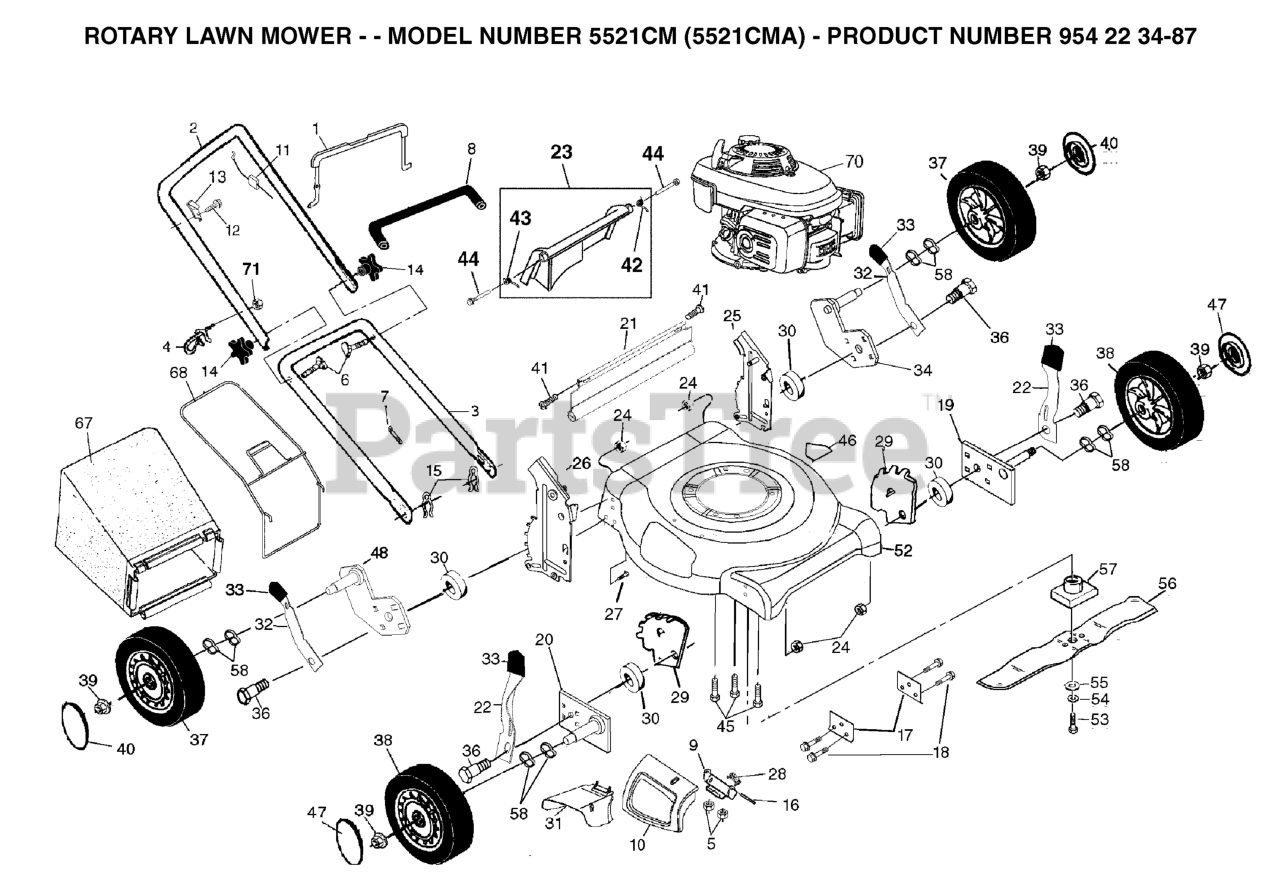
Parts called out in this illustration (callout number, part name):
1	CONTROL BAR
2	UPPER HANDLE, WITH GRIP
3	HANDLE.LOWER.GREY
4	ROPE, GUIDE
5	NUT
6	HANDLE BOLT
7	TIE GUIDE
8	GRIP.HANDLE.FOAM
9	BRACKET.ASM.HOUSING.EZ.MUL
10	RP DOOR.MULCH.21".REAR.PUSH.GR
11	ENGINE ZONE CONTROL CABLE
13	BRACKET
14	KNOB.HANDLE.STAR.HUSQ.GRAY
15	HAIRPIN COTTER
16	ROD.HINGE.COMBI-C
17	SUPPORT BRACKET
18	SCREW 1/4X20
19	AXLE ARM ASM (L)
20	AXLE ARM ASM
21	REAR DEFLECTOR, POULAN PR6N22
22	REPL BY 532 1683-60
23	REAR DOOR ASSEMBLY KIT
24	NUT.CENTERLOCK.5/16-
25	HANDLE BRACKET ASSEMBLY, LEFT
26	HANDLE.BRKT.ASSY.RIGHT.BLACK
27	SCREW
28	TORSION SPRING
29	WHEEL BRACKET ADJUSTER
30	SPACER.34X1.38X.22
31	DEFLECTOR.CLIPPING.21.GREY
32	SELECTOR SPRING, REAR
33	SELECTOR KNOB
34	AXLE ARM ASSY 10"
36	SHOULDER BOLT
37	WHEEL.10X2.PR.HITRAC.BLACK
38	WHEEL 8 X 2 BLACK BALL BEARING
39	HEX FLANGE LOCKNT
40	HUBCAP.10.MAG.SILVER
41	HINGE SCREW
42	SPRING (LH)
43	SPRING (RH)
45	BOLT 3/8-16X1-1/8
46	DECAL HYT
47	HUBCAP
48	ARM ASM AXLE 10"
52	HOUSING ASSEMBLY
53	SCREW, HEX HD 3/8-24 X 1-3/8
54	LOCKWASHER
55	WASHER,HARDEN
56	BLADE
57	BLADE ADAPTOR
58	WAVE WASHER
67	GRASS BAG
68	CATCHER FRAME
71	NUT
